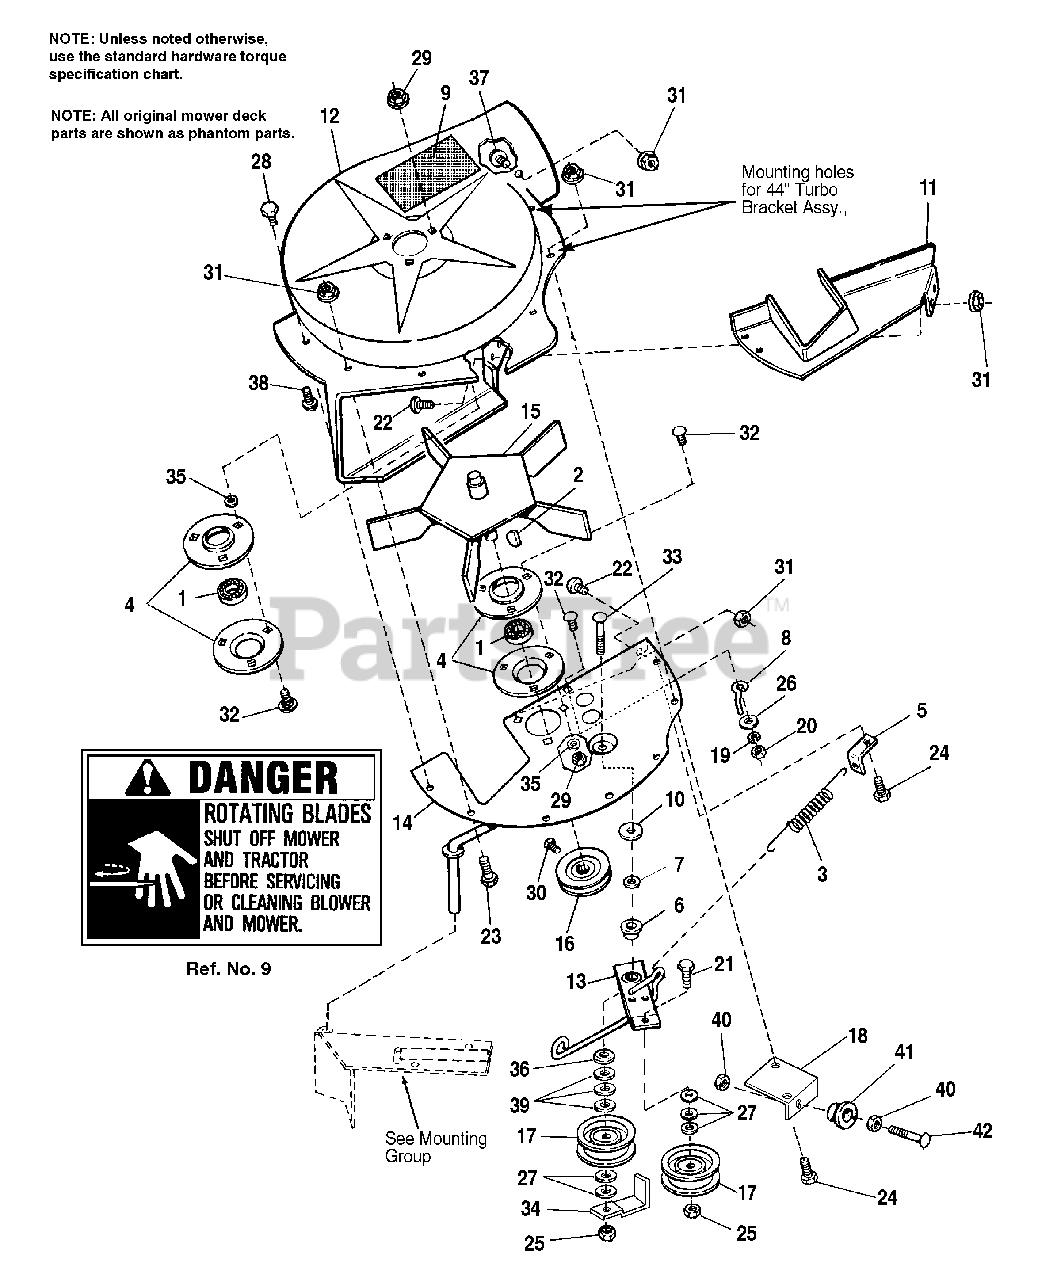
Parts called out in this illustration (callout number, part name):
2	KEY, Woodruff, Modified
3	SPRING, Tension
4	BEARING, Retainer
5	BRACKET, Anchor, Spring
6	SPACER, Idler Arm
7	PUSHNUT, 3/8
9	DECAL, Danger, Blower
10	WASHER, Plain
11	PLATE, Cover
12	FAN HOUSING
13	LEVER ASSY, Turbo
14	PLATE ASSY.
15	FAN ASSY., 5 Blade
16	PULLEY, Driven
17	IDLER PULLEY ASSY.
18	BRACKET ASSY., Turbo
19	WASHER, Spring Lock, 5/16
20	NUT, Hex, 5/16
21	CAPSCREW, 3/8-16 X 1-1/2
22	SCREW, Truss Hd., 1/4-18 x 5/8
23	CAPSCREW, Hex, 1/4-20 x 5/8
24	CAPSCREW, Hex Hd., 1/4-20 x 3/4
25	NUT, 3/8-16
26	WASHER, Flat
27	WASHER, Plain
28	CAPSCREW, Hex, Taptite, 1/4-20 x 1/2
29	NUT, Flange, Whizlock, 5/16-18
30	SETSCREW, Hex, Socket Hd., 5/16-18 x 5/16
31	NUT, Hex, Flange Lock, 1/4-20
32	CARRIAGE BOLT, 5/16-18 x 3/4
33	CARRIAGE BOLT, 3/8-16 x 2-1/4
35	PUSH NUT, 3/8
36	WASHER
37	CARRIAGE BOLT, 1/4-20 x 5/8
38	SCREW, Washer Hd., 1/4-18 x 5/8
39	WASHER
40	NUT, Whizlock, 5/16-18
42	CARRIAGE BOLT, 5/16-18 x 2-1/2
